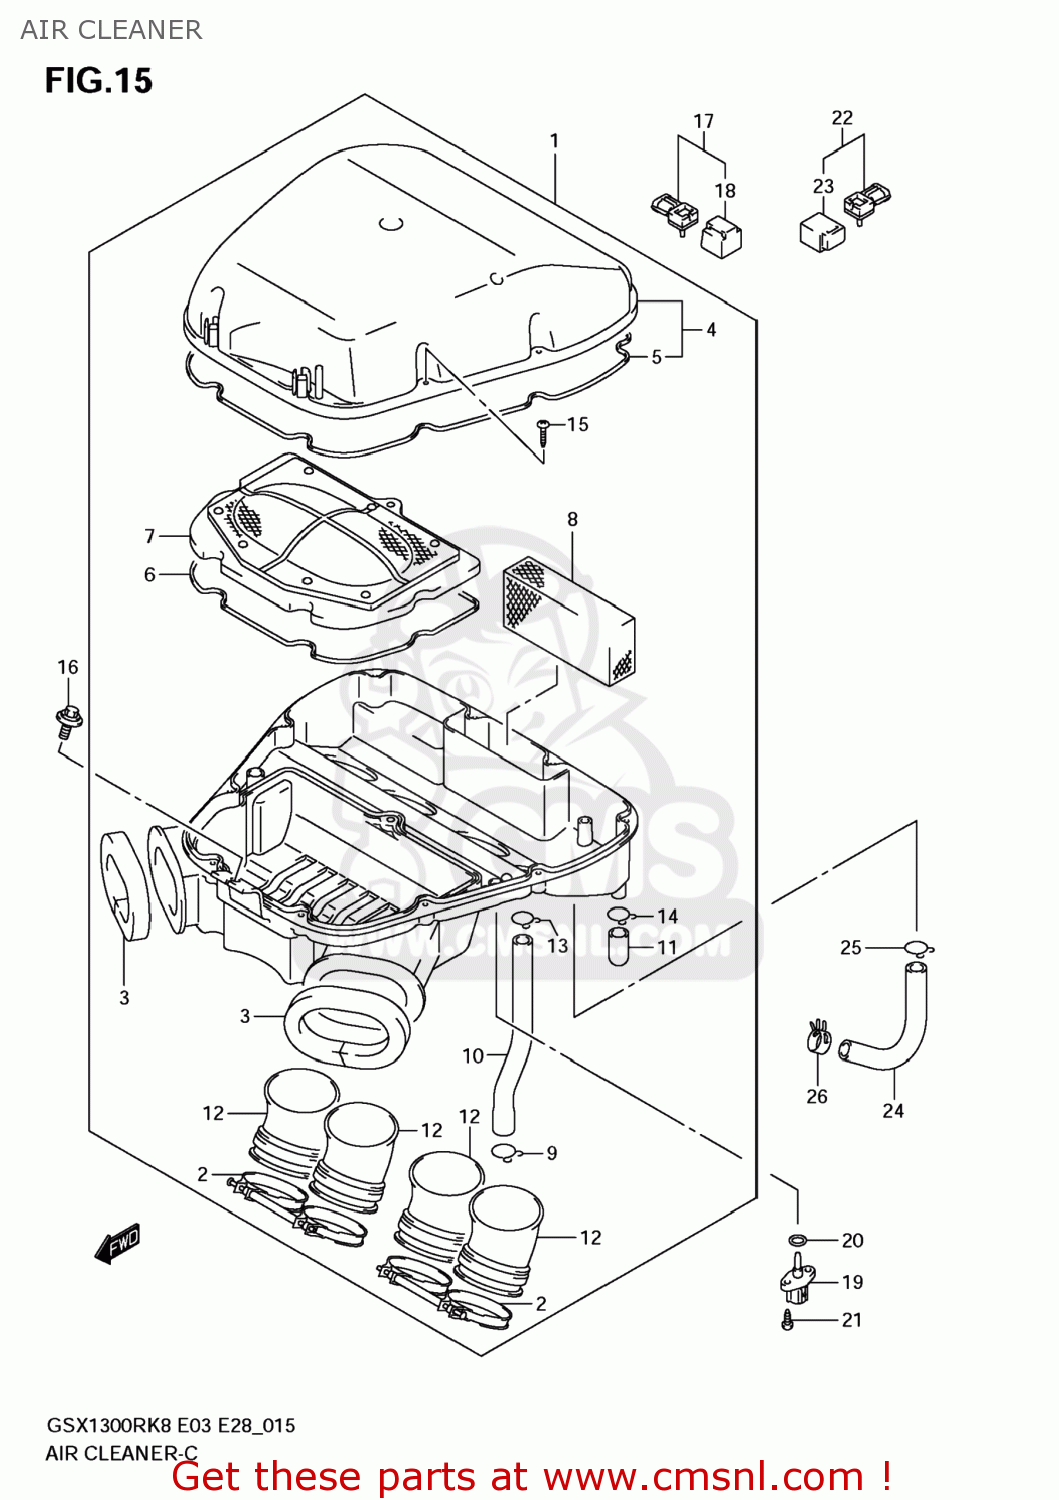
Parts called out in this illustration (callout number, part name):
1	CLEANER ASSY,AIR
2	CLAMP,INTAKE PIPE
3	CUSHION,DUCT
4	CAP,AIR CLEANER
5	GASKET,CAP (NAS)
6	GASKET,CASE (NAS)
7	FILTER ASSY
8	FILTER,BREATHER
9	CLIP
10	TUBE,BREATHER
11	PLUG
12	TUBE,OUTLET B
13	CLIP
14	CLIP
15	SCREW
16	BOLT(6X16)
17	SENSOR,BOOST
18	COVER
19	SENSOR,AIR TEM
20	O RING
21	SCREW
22	SENSOR,AIR PRESSURE
23	COVER
24	HOSE,ISC VALVE
25	CLIP
26	CLIP
